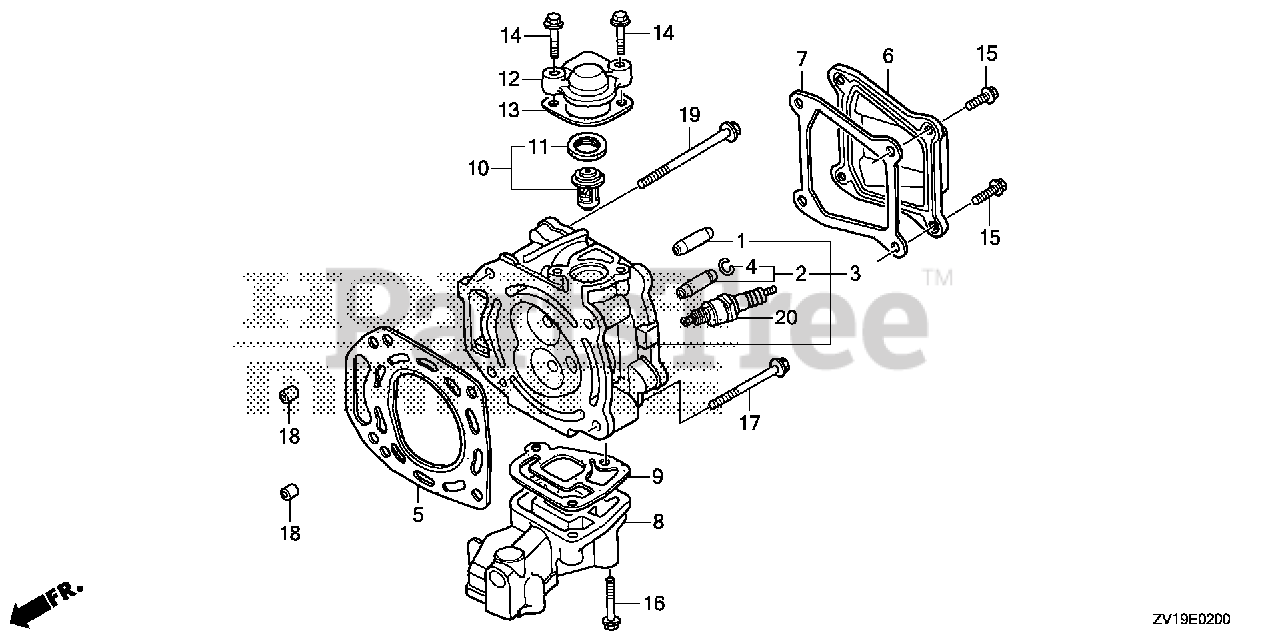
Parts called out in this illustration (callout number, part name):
1	GUIDE, VALVE (OVER SIZE) Use from Engine SN 6324986.
2	GUIDE, EX. VALVE (OS)
3	CYLINDER HEAD *NH8* (DARK GRAY)
4	CLIP, VALVE GUIDE Use from Engine SN 1231803.
5	GASKET, CYLINDER HEAD
6	COVER, HEAD
7	GASKET, CYLINDER HEAD COVER
8	MANIFOLD, EX. *NH8* (DARK GRAY)
9	GASKET, EX. MANIFOLD
10	THERMOSTAT ASSY.
11	RUBBER, THERMOSTAT
12	COVER, THERMOSTAT *NH8* (DARK GRAY)
13	GASKET, THERMOSTAT COVER
14	BOLT, FLANGE (6X23)
15	BOLT, FLANGE (6X12)
16	BOLT, FLANGE (6X32) (CT200)
17	BOLT, FLANGE (8X60)
18	PIN A, DOWEL (10X16)
19	BOLT, FLANGE (8X90)
20	SPARK PLUG (BPR5ES) (NGK)
